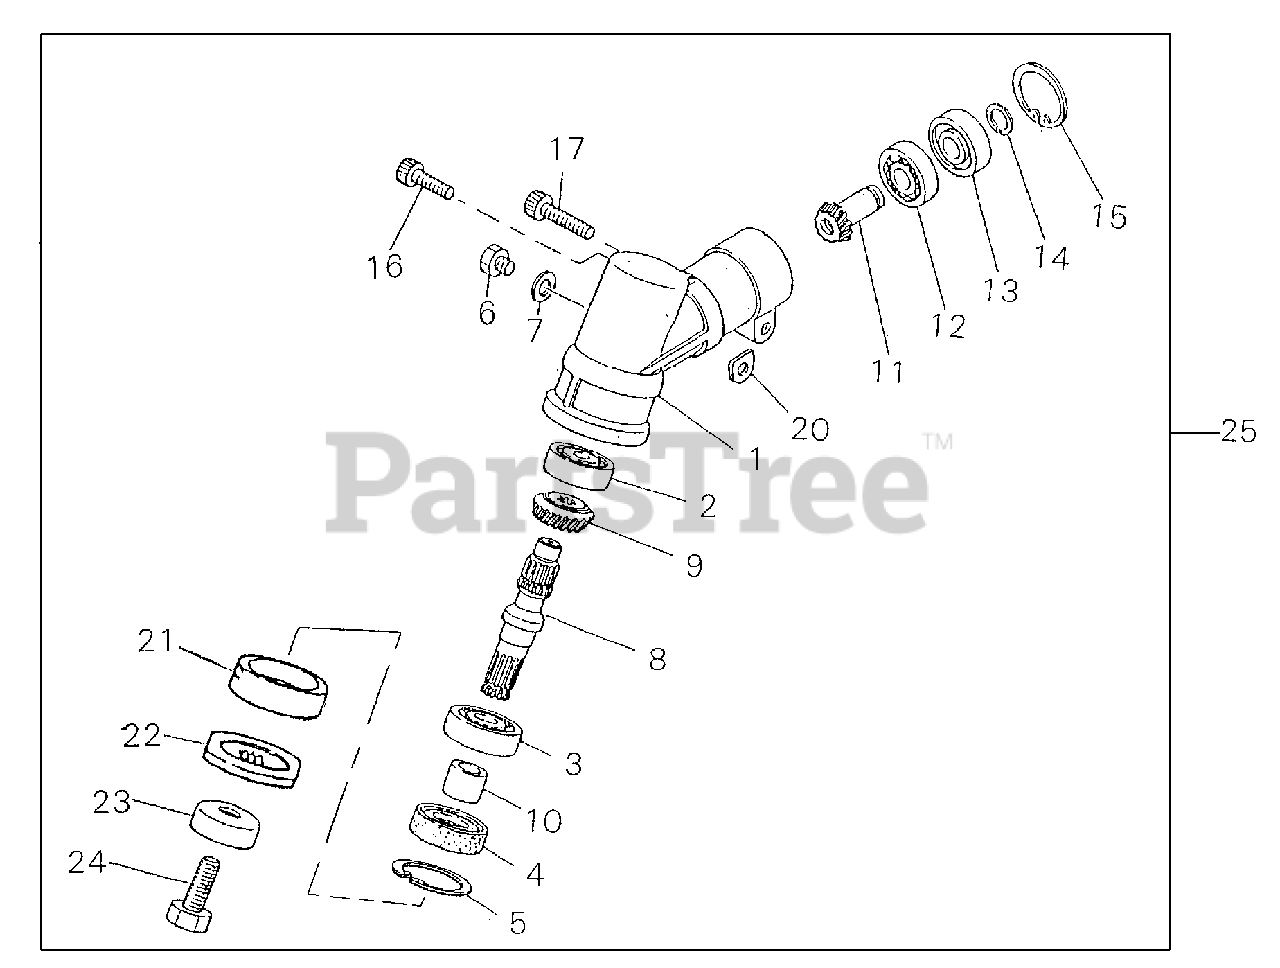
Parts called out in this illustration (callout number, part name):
1	CASE, GEAR
2	BEARING, BALL - 626
3	BEARING, BALL - 6000
4	SEAL, OIL
5	RING, RETAINING - 26
6	BOLT - 6X10
7	WASHER
8	GEAR - SHAFT
9	GEAR - BEVEL
10	COLLAR
11	GEAR - SHAFT
12	BEARING, BALL - 608
13	BEARING, BALL - 608ZZ
14	RING, RETAINING
15	RING, RETAINING - 22
16	SCREW - 5X12
17	SCREW - 5X25
20	SHIM
21	HOLDER - A
22	HOLDER B, REPLACES 22035-13251, REPLACES 22553-13250
23	GUARD
24	BOLT - 7X18 -- LEFT HAND
25	GEAR CASE ASSY
